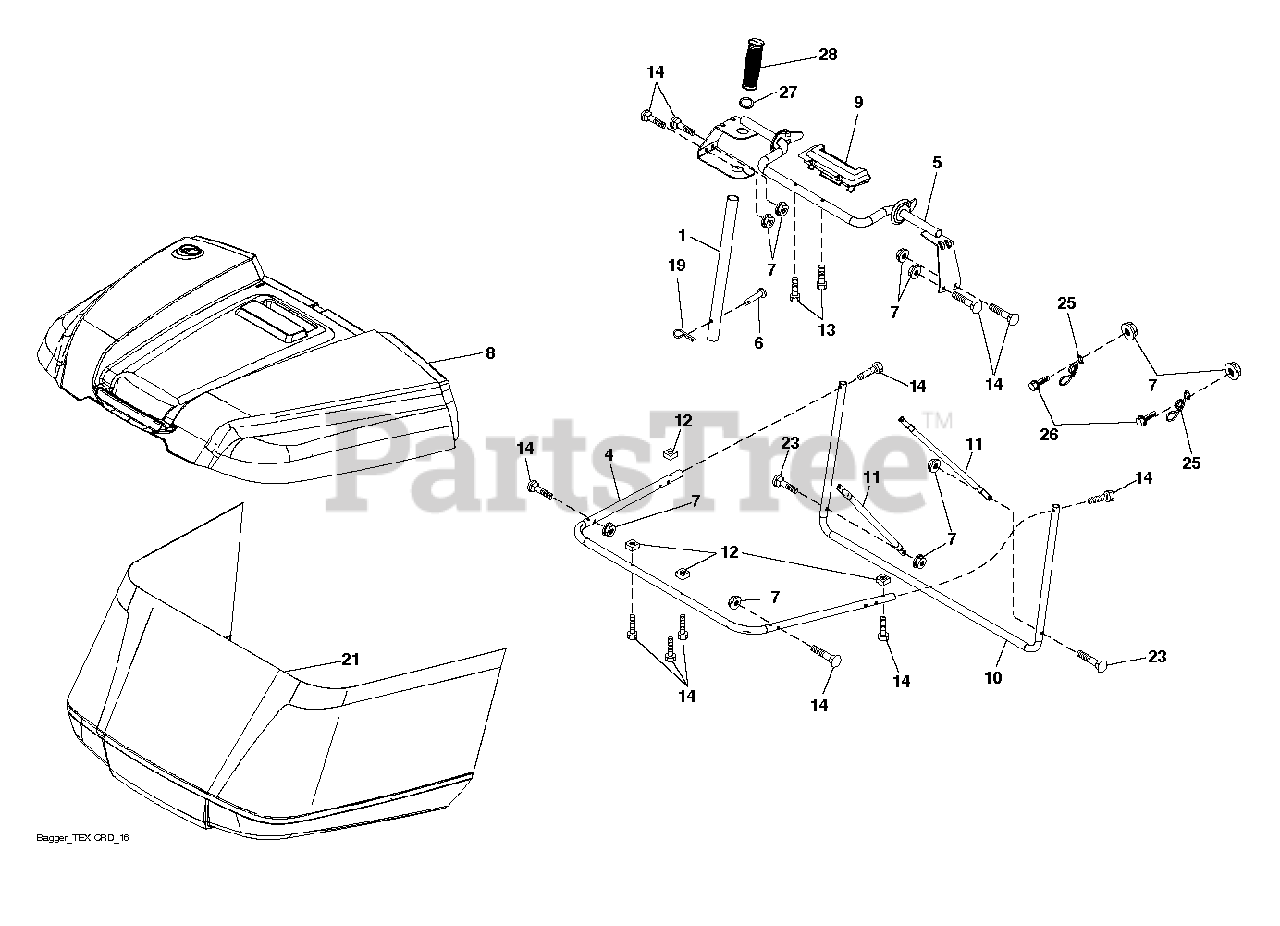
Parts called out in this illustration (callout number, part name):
1	TUBE.PNT.HDL.BAGGER.
6	RIVET,DRILLED
7	NUT T
19	PIN.COTTER.5/16.BOW TI
26	SCREW HEX CRT
28	GRIP.HANDLE.BLACK
